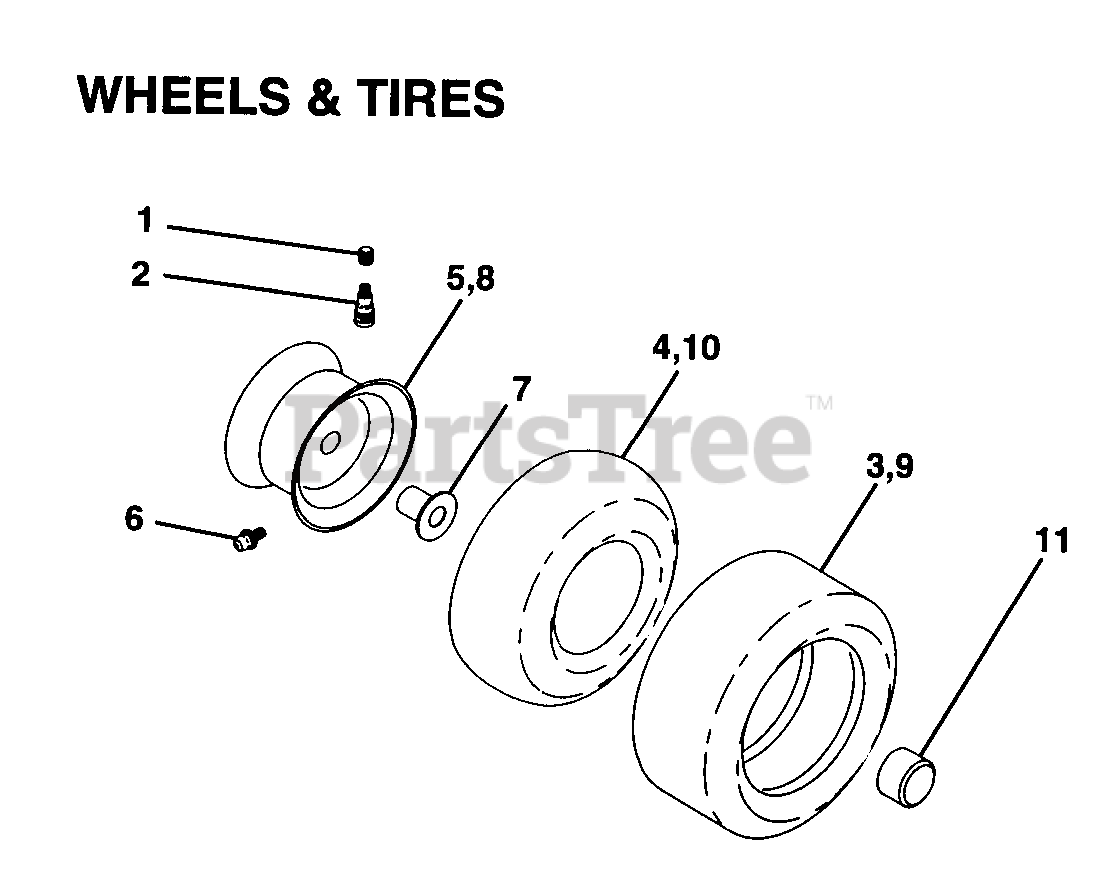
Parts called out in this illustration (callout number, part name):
2	VALVE STEM LT
3	TIRE HEAVY DUTY
4	TUBE.5.3/4.5/6
5	RIM ASM 6" FRONT SILVER
6	FITTING LT
7	BEARING T
8	RIM ASM 8" REAR SILVER
9	TIRE.TS.20X10-8
10	TUBE
11	CAP.HUB.FRONT.LT.BLACK
